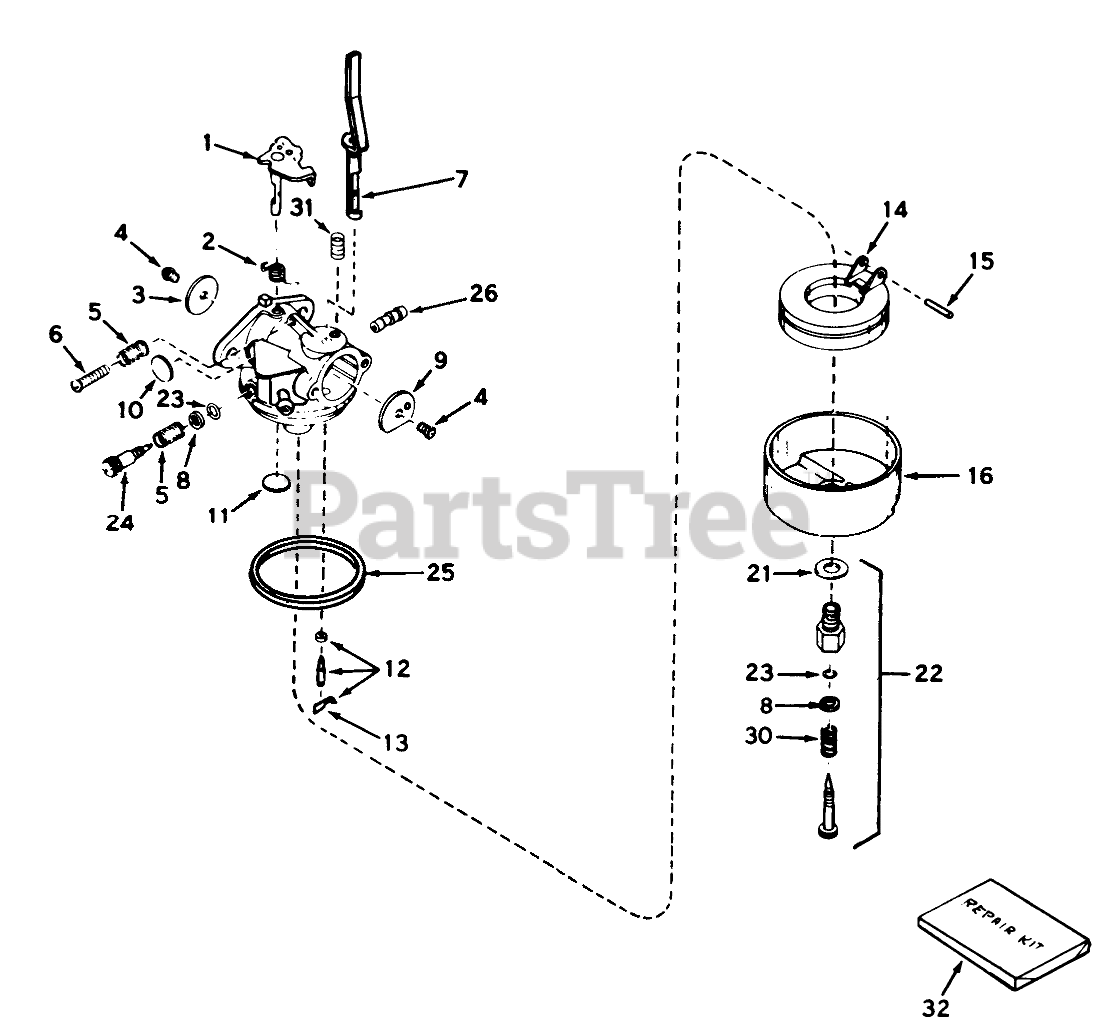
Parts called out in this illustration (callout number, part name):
1	Shaft/Lever-Throttle
2	Spring, Return
3	Shutter-Throttle
4	Screw-Shutter
5	Spring-Tension
6	Screw-Throttle Crack Screw / Idle Speed
7	Shaft & Lever Assy., Choke
9	Shutter-choke
10	Plug-Welch, Idle Mixture Well
11	Plug-Welch, Atmospheric Vent
12	Inlet Needle, Seat & Clip Assy. (Incl. No. 13)
13	Clip-Spring
14	Float,Carburetor
15	Shaft-Float
16	Bowl-Float (no drain)
21	Washer-Bowl Nut
22	Adjustment Screw Assy., Main (Incl. Nos. 8, 21, 23 & 30)
23	"O"Ring
24	Screw, Idle Adj.
25	O Ring-Bowl, Float
26	Fuel Fitting
31	Spring-Positioning, Choke
32	Kit-Repair
